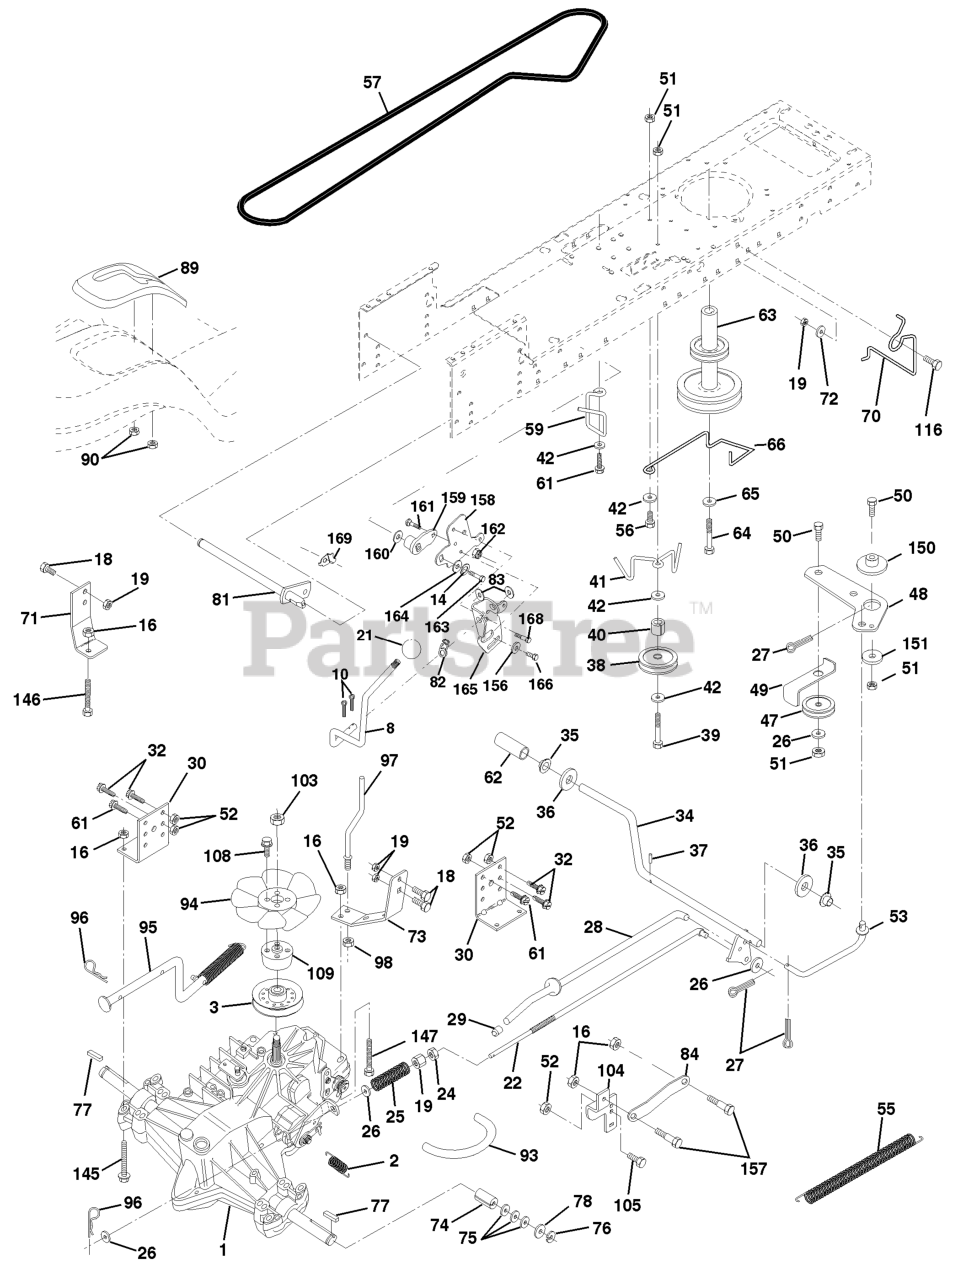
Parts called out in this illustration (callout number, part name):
1	TRANSAXLE.HYDRO.319-0500.LR
2	SPRING BRAKE
3	PULLEY.4.20.HYDRO
8	ROD SHIFT FENDER ADJUST STLT
10	PIN COTTER
14	LOCKWASHER
16	NUT.71038.31-18.HEX.NYLOCK
18	BOLT
19	NUT
21	KNOB.DUCKHEAD.1/2
22	ROD BRAKE HYDRO
24	NUT
25	SPRING ROD LT
26	WASHER
27	COTTER PIN
28	ROD BRAKE PARK LT
29	PLUNGER CAP
30	BRACKET TRANSAXLE
32	BOLT
34	SHAFT, FOOT PEDAL
35	BEARING.NYLON
36	WASHER LT
37	DRIVE PIN
38	FLAT IDLER PULLEY
41	KEEPER.BELT.IDLER.FLAT
42	WASHER
47	IDLER PULLEY
48	BELLCRANK, CLUTCH
49	RETAIN BELT
50	BOLT
52	LOCKNUT
53	LINK, CLUTCH LT
55	SPRING, RETURN LT
59	KEEPER CENTER SPAN
61	SCREW
62	PEDAL COVER T
63	PULLEY.ENG.CL.MECH.SLVR.LT/YT
64	BOLT
65	LOCKWASHER
66	KEEPER BELT ENGINE
70	KEEPER BELT ENG
71	STRAP TORQUE LH HYDRO
72	WASHER
73	STRAP TORQUE RH HYDRO
74	SPACER SPLIT
77	SQUARE KEY
81	Shaft Asm. Cross Tapered
82	SHIFT SPRING
83	WASHER
84	Link Transaxle
89	SHIFT CONSOLE
90	NUT.PUSH.3/16
93	LINE FUEL HYD 4"
94	FAN 7" HYDRO
95	CONTROL ARM, BYPASS HYDRO
96	RETAINER M
97	KEEPER BELT RH
100	WASHER M
103	NUT.HEX.1/2-20
104	ARM, CONTROL HYDRO
106	BOLT.5/16-18X1-1/4 FULL.THREAD
109	ADAPTOR FAN HYDRO
116	BOLT
144	Washer 11/32 x 5/8 x 16 Ga.
145	BOLT
146	Bolt Hex Flg Hd 5/16-18 x 2-1/4
147	Bolt Hex Flg Hd 5/16-18 x 1-1/2
149	SPACER RETAINER
150	BUSHING.BELLCRANK.GRD.DR
151	WASHER 12/32X2X10GA
156	WASHER.SRRTD.5/16
157	BOLT SHOULDER 5/16-18
158	BRACKET
159	HUB
160	Washer 29/32 x 1-1/4 x 16 Ga.
161	BOLT
162	NUT.CROWNLOCK.1/4
163	BOLT
164	Washer 5/8 x .281 x 10 Ga
165	RP BRACKET
168	BOLT.SHOULDER.5/16-18X
169	PLATE.FASTENING.CROSS.SHAFT
